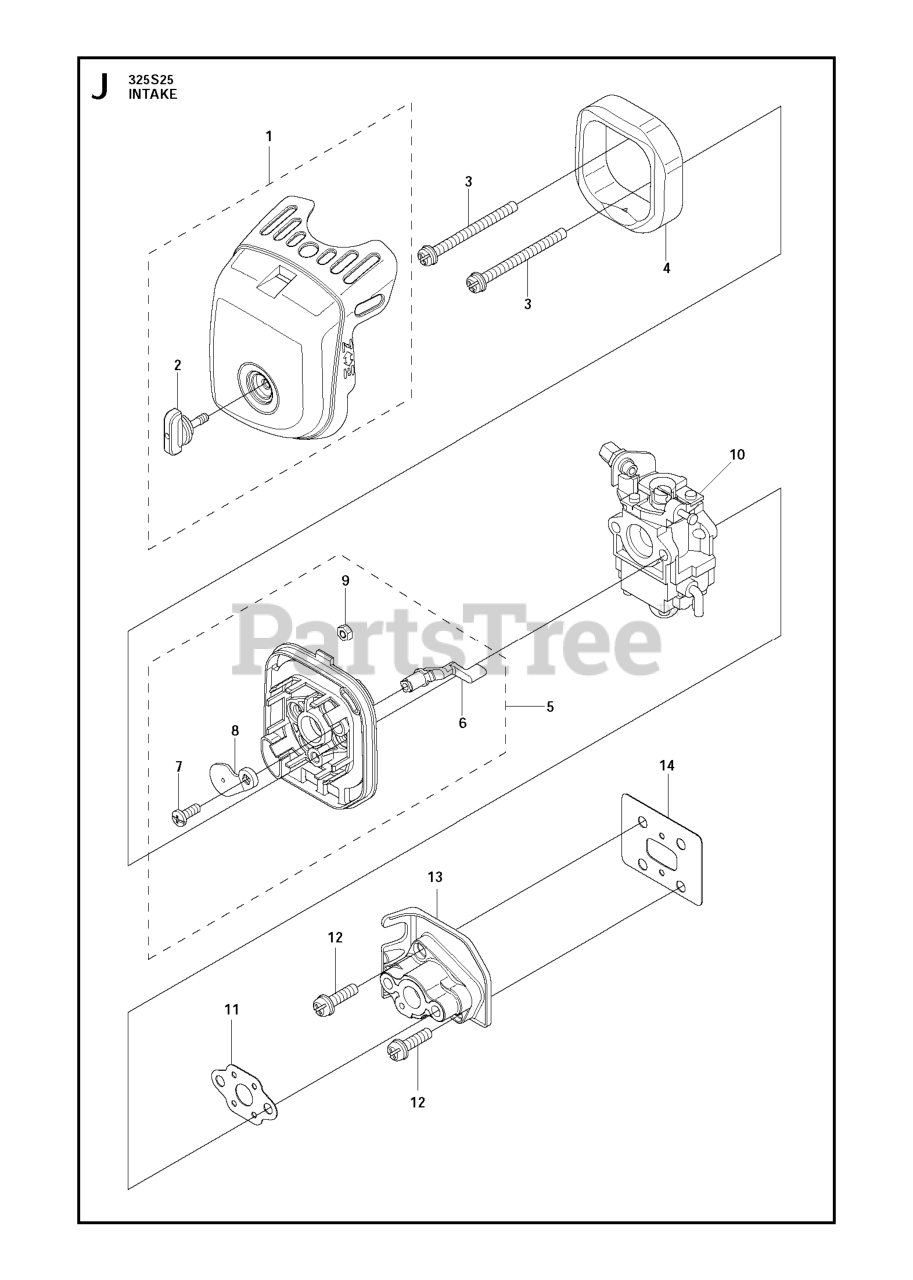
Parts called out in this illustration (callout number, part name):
7	SCREW
8	PLATE.CHOKE
10	CARBURETOR ASSEMBLY
